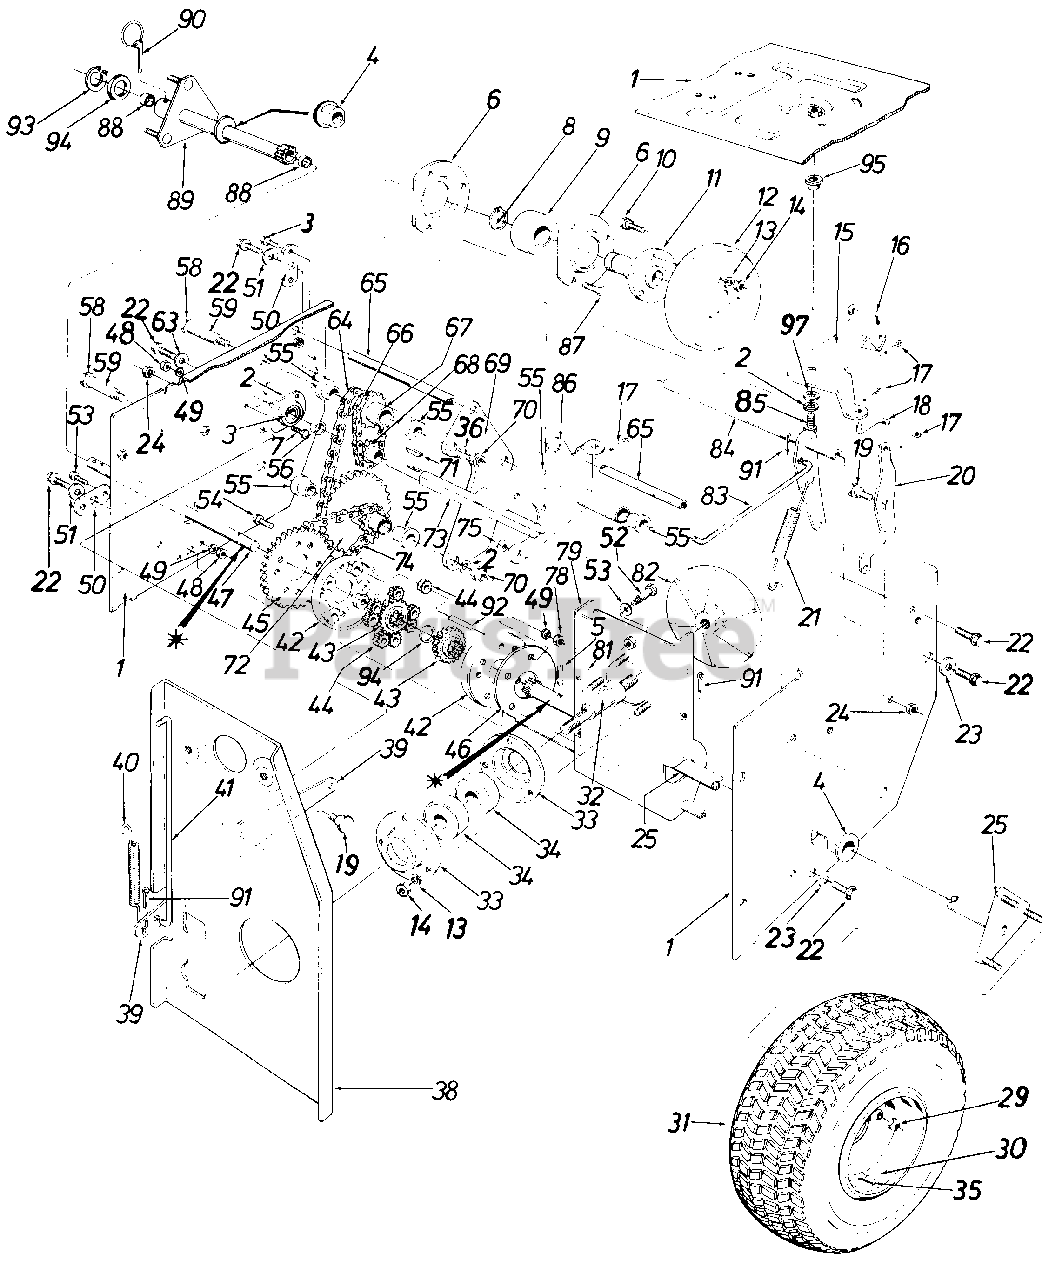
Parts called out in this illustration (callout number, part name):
1	Frame Ass'y.
2	L-Wash. 3/8" I.D.
3	Hex Bolt 1/4-20 x .62" Lg.
4	Flange Brg. w/Flats 1.00" I.D.
5	H-Spring Pin Spiral 3116" Dia. x 1.25" Lg.
6	Bearing Housing
8	Snap Ring 1.00" Dia.
9	Ball Brg. 25 mm x 52 mm x 15 mm Thk.
10	Hex Sems Scr. 5/16-18 x .75" Lg.
11	Friction Wheel Adapter
12	Friction Wheel Ass'y.
13	L-Wash. 5/16" Scr.
14	Hex Nut 5/16-18" Thd.
15	Sliding Linkage Brk't.
16	Sliding Rod .31" Dia. x 2.00" Lg.
17	Cot. Pin 3132" Dia. x .75" Lg.
18	Shifting Linkage Rod .31" Dia. x 2.25" Lg.
19	Shld. Scr. .625" Dia. x .170"
20	Shifting Linkage Brk't.
21	Extension Spring .73 O.D. x 4.31" Lg.
22	Hex L-Scr. 5/16-18 x .62" Lg.
23	Fl-Wash. .345 I.D. x .75 O.D.
24	Hex Cent. L-Nut 3/8-16 Thd.
25	Differential Shaft Ass'y. L.H.
29	Cone Nut 3/8-24 Thd.
30	Wheel Rim Ass'y.
31	Wheel Ass'y. Comp. 16.0 x 6.50
32	Drive Plate Spindle
33	Bearing Housing
34	Ball Brg. .787 I.D. x 1.85 O.D.
35	Air Valve
36	Bearing Housing
38	Engine Brk't. Ass'y.
39	Auger Clutch Brk't.
40	Extension Spring .38 O.D. x 3.18" Lg.
41	Auger Clutch Rod .31" Dia. x 10.62" Lg.
42	Differential Housing
43	20 Tooth Spur Gear
44	9 Tooth Spur Gear
45	28 Teeth Sprocket
46	Differential Hsg. Support Plate
47	Differential Connecting Shaft
48	Hex Nut 1/4-20 Thd.
49	L-Wash. 1/4" Scr.
50	Pivot Axle Brk't.
51	Fl-Wash. .345" I.D. x .75" O.D.
52	Shld. Scr.
53	Bell-Wash.
54	Hex Scr. 1/4-28 x 1.75" Lg.
55	Flange Brg. .630" I.D.
56	Spacer.51" I.D. x .69" O.D.
58	Hex Scr. 3/8-24 x 2.75" Lg.
59	Sprocket Hub Tubing 1.900" Lg.
63	Bell-Wash. .345" I.D. x .88 O.D.
64	#41 Chain 1/2" Pitch x 43 Links
65	Sliding Support Axle
66	#41 Chain 1/2" Pitch x 19 Links
67	9 and 14 Teeth Sprocket Hub Ass'y.
68	8 Teeth Sprocket
71	#9 Hi-Pro Key 3/32 x 5/8" Dia.
72	9 and 32 Teeth Sprocket Hub Ass'y.
73	Hex Shaft
74	#420 Chain 1/2" Pitch x 37 Links
75	Hex Ins. Jam L-Nut 1/4-28"
78	Hex Nut 1/4-28 Thd.
82	Aluminum Drive Plate
83	Drive Clutch Rod .31" Dia. x 7.38" Lg.
84	Drive Clutch Brk't. Ass'y.
85	Hex Scr. 3/8-16 x 1.00" Lg.
86	Sliding Brk't. Ass'y.
87	Hex Scr. 1/4-28 x .62" Lg.
88	Sleeve Brg.
89	Differential Tubing Ass'y. R.H.
90	Klick Pin 1/4" Dia. x 1.75" Lg.
91	Internal Cot. Pin 5/16 Dia.
92	Differential Pin
93	Snap Ring .625 Shaft
94	Fl-Wash. .62 I.D. x 1.25 O.D.
95	Shld. Spacer 5/8" I.D.
97	Fl-Wash.
